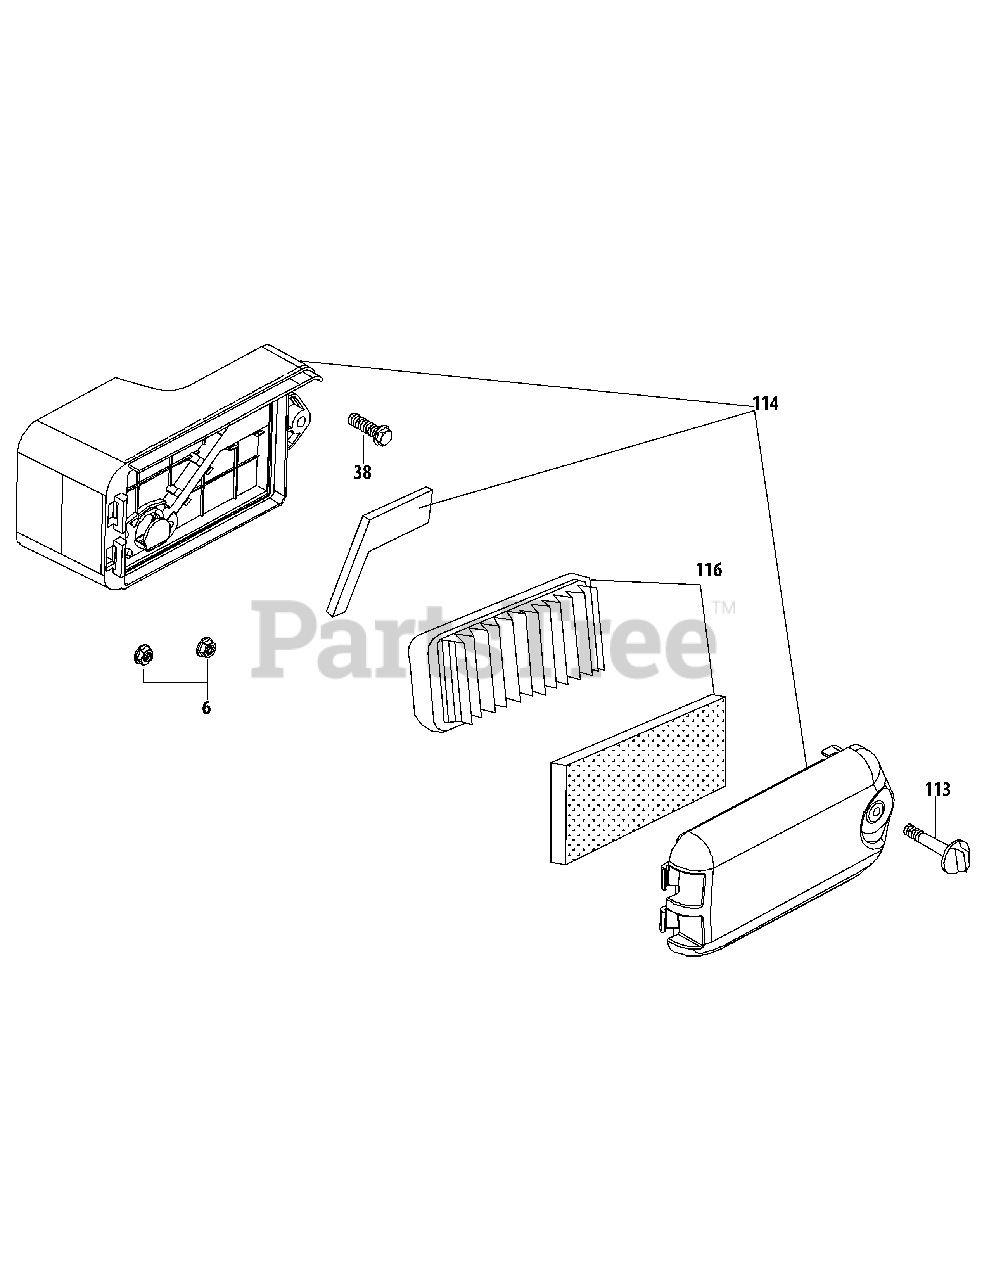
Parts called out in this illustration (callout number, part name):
6	Nut M6 X 10 Mm
38	Bolt M6X35
113	Air Filter Cover Thumb Screw
114	Air Filter Kit
116	Air Cleaner Assembly
